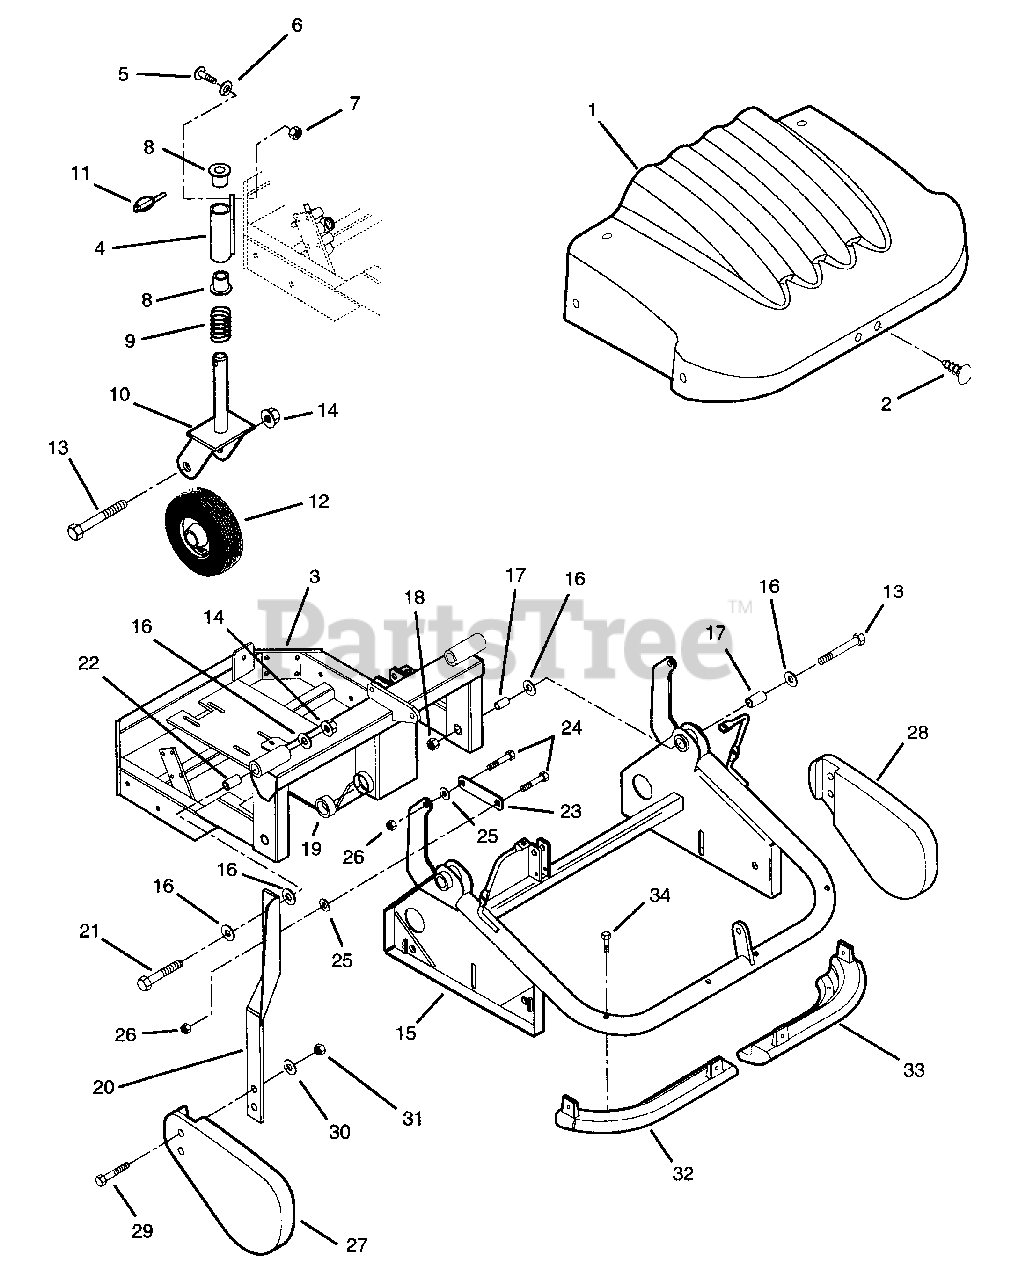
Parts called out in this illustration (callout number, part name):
2	Push Fastener
3	Rear Frame Weldment
4	Castor Mount Weldment
5	Bolt-Round Head Square Neck .38-16 x 1.0Grade 5
6	Washer-Lock .375 x .094
7	Nut-Hex .375-16 Grade 2
8	Bearing-Flange 1.50 OD x .125
9	Spring-Compression
10	Wheel Fork Weldment
11	Pin-Lock .31-2.00
12	Tire/Wheel Assembly 6.25 x 3.00
13	Bolt-Hex .75-10 x 4.50
14	Nut-Locking Unitorque .75
15	Front Frame Weldment
16	Washer-Flat .812 x 1.469 x .134
17	Bushing-Sleeve 1.0 OD x .75 ID x 2.0 LG
18	Nut-Locking 2-Way .75
19	Bearing-Schultz
20	Counter Pendulum Right Hand
21	Bolt-Hex .75-10 x 5.50
22	Bushing-Sleeve 1.0 OD x .75 ID x 1.50 LG
23	Pendulum Link
24	Bolt-Hex .50-13 x 1.25 Grade 5
25	Washer-Flat-Steel .531 x 1.062 x .095
26	Nut-Locking Unitorque .50
27	Side Weight - Right Hand
28	Side Weight - Left Hand
29	Bolt-Hex .50-13 x 1.75
30	Washer-Lock .50 Reg
31	Nut .50-13
32	Counter Weight - Right Hand
33	Counter Weight - Left Hand
34	Bolt-Hex .38-16 x 2.75 Plated Grade 5
